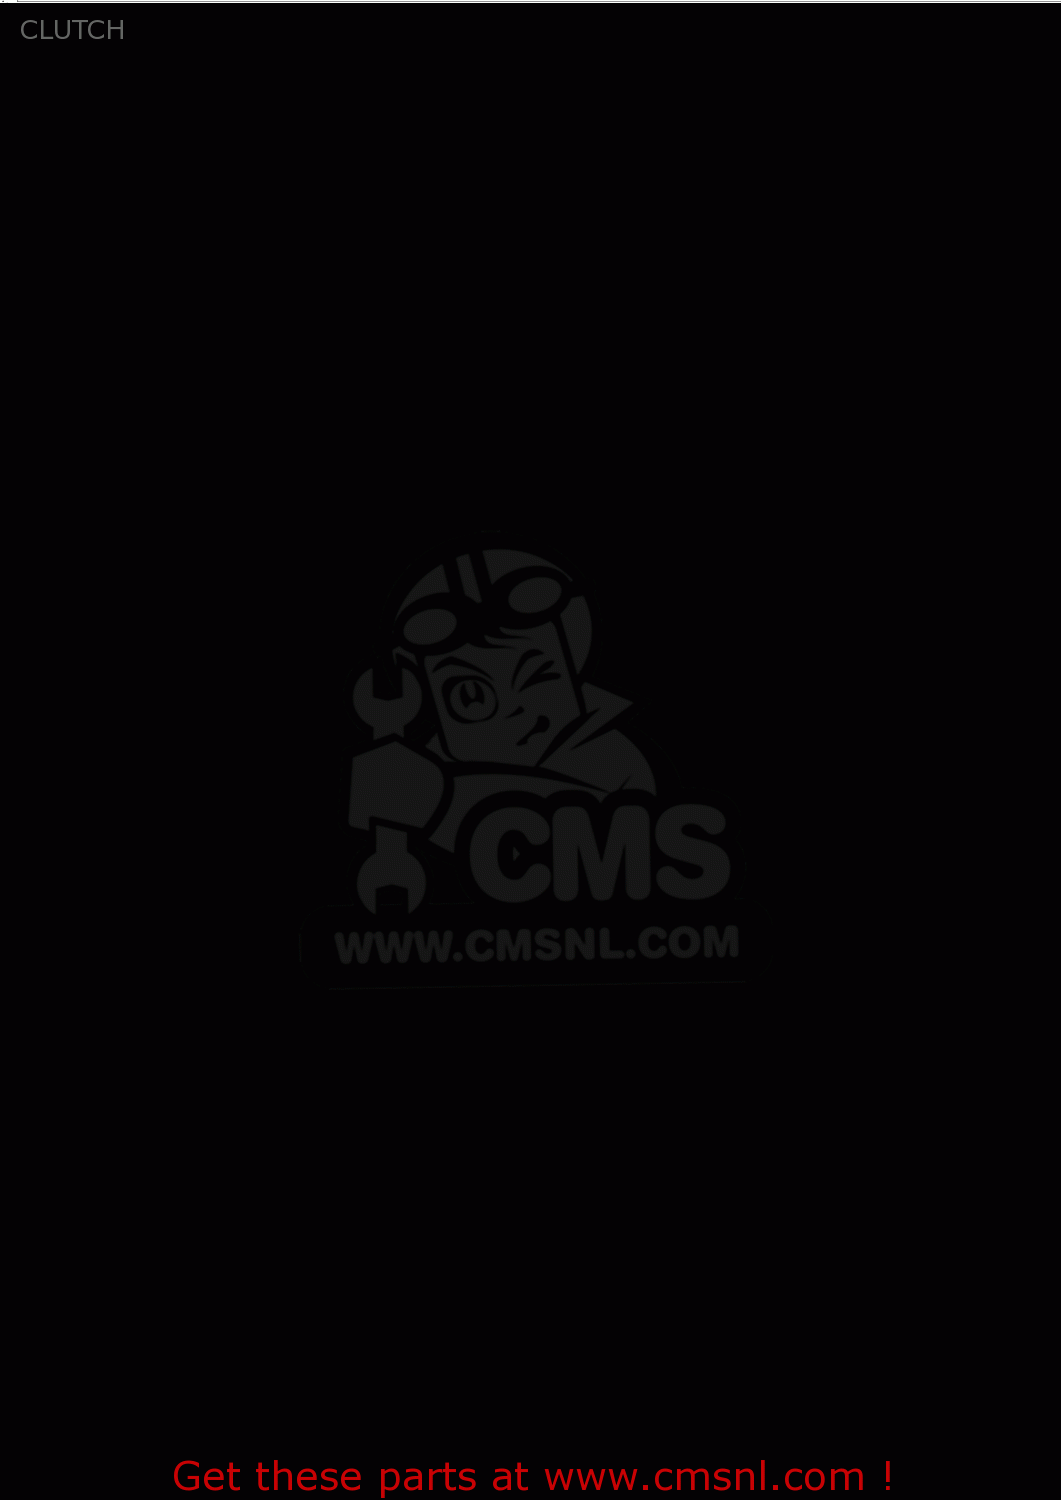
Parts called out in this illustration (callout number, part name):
1	GEAR ASSEMBLY,PRIMARY DRIVE
2	WASHER
3	WASHER
4	BEARING(40X45X32)
5	HUB,CLUTCH SLEEVE
6	NUT
7	WASHER,LOCK
8	WASHER
9	PLATE,CLUTCH DRIVE (NAS)
10	PLATE,CLUTCH DRIVEN (NAS)
11	PLATE,CLUTCH DRIVEN(T:2.0) (NAS)
12	DISC,CLUTCH PRESSURE
13	SPRING
14	BOLT, UPPER
15	WASHER
16	SEAT,WAVE WASHER
17	RING,STOPPER
18	WASHER
19	PIECE,CLUTCH PUSH
20	BEARING(15X28X2)
21	WASHER
22	GEAR,OIL PUMP DRIVE
23	PIN
24	ROD,CLUTCH PUSH
25	ROD,CLUTCH PUSH,L
26	OIL SEAL
27	PLATE,CLUTCH PUSH ROD
28	BOLT
29	SCREW ASSY,CLUTCH RELEASE
30	SCREW(6X25)
31	NUT 6MM
32	SCREW
33	SPRING
